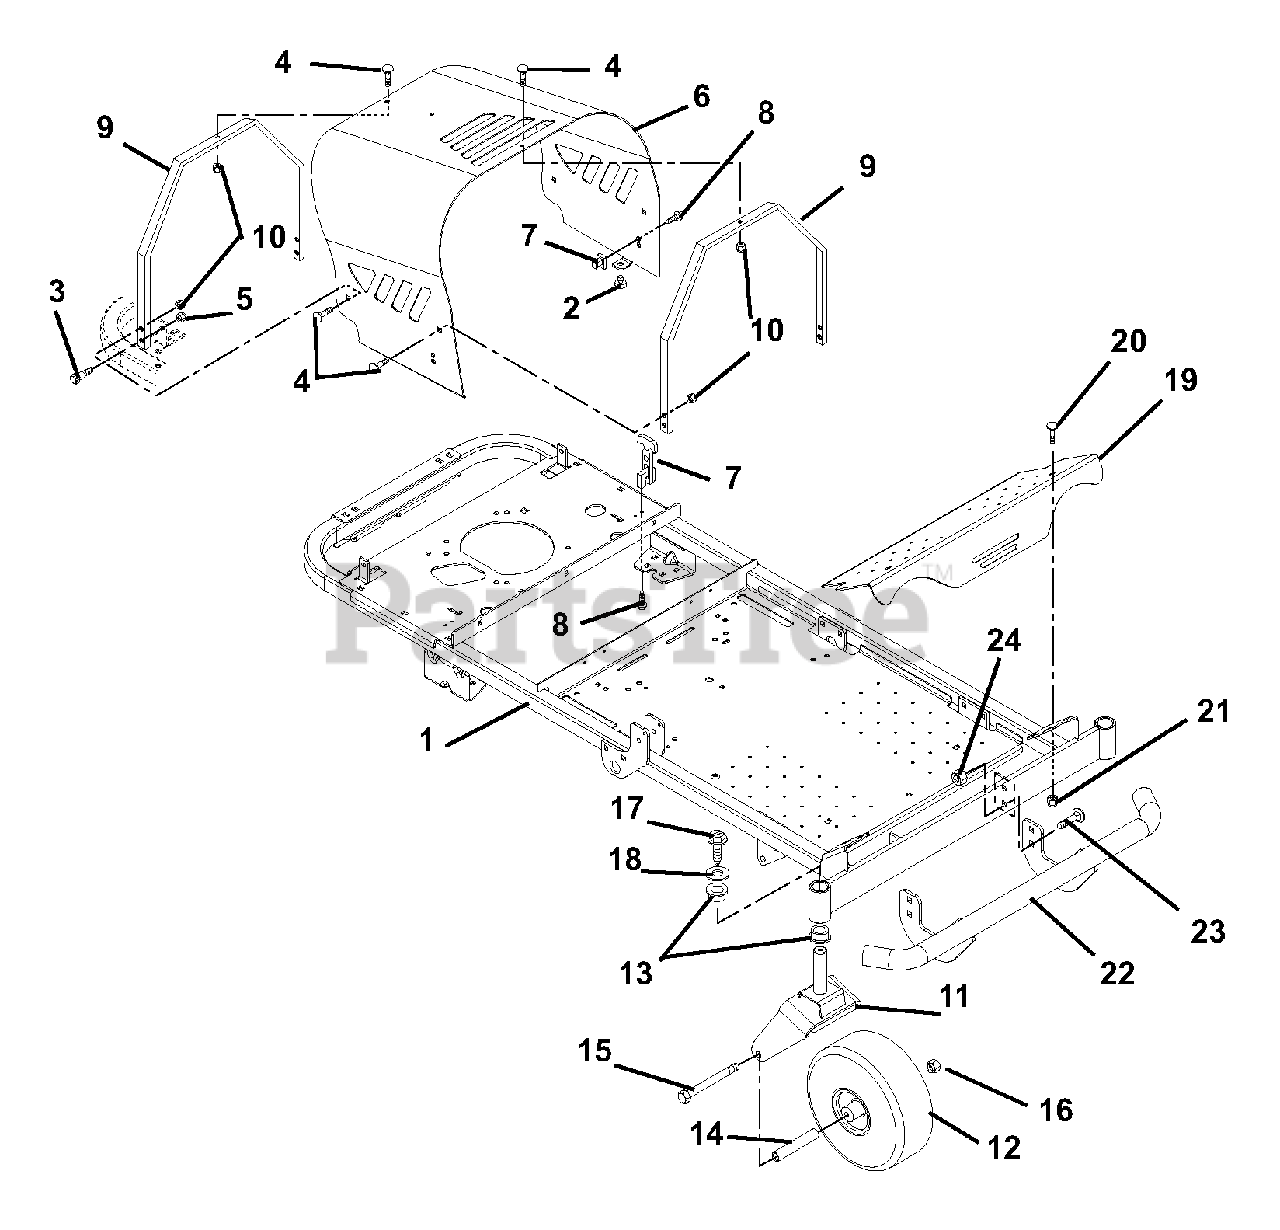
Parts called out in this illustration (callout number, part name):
1	WMT, FIXED AXLE FRAME
2	BUTTON BUMPER
3	BOLT-SHLDR .375-16X.150
4	@BLT-RHDSSQNK .31-18X.62 G5YZ
5	@NUT-LK-TOP-FLG .38-16 YWZC
6	HOOD, ZOOM
7	LATCH, RUBBER
8	@SCR-MCH 10-24X.50 HWH YWZC
9	BRACE, HOOD
10	@NUT-LK-TOP-FLG .31-18 YWZC
11	FORK - CASTER
12	ASSY-TIRE 4 X 11 - 4 PLY
13	BSHG-FLG 1.00X1.25X1.50X1.50EP
14	SPACER, ROLLED WHEEL
15	@BLT-HEX .50-13X6.50 GR5 YWZC
16	@NUT-LK-TOP-FLG .50-13 YWZC
17	SCR-TAP .38-16X1.25 HWH TR BZC
18	WSHR-FL-STL .380X1.50X.125YWZC
19	FOOT REST
20	@BLT-RDHDSQNK .38-16X1.00 G5YZ
21	@NUT-LK-NYL-FLG .38-16 YWZC
22	BUMPER-ZOOM
23	@BLT-RDHDSQNK .38-16X1.00 G5YZ
24	@NUT-LK-NYL-FLG .38-16 YWZC
